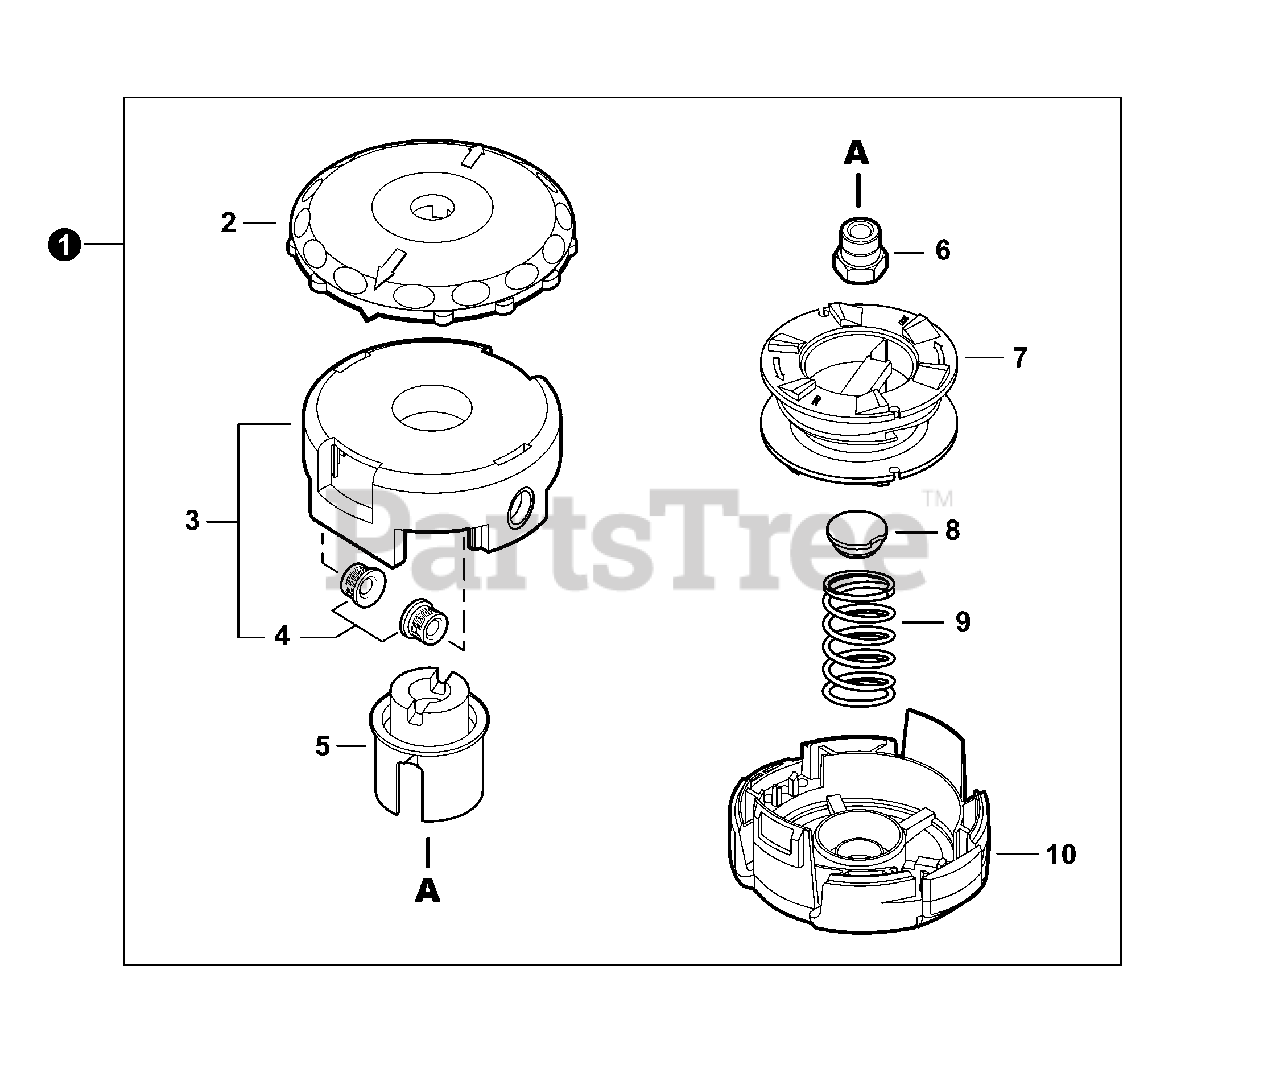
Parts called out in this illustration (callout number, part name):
1	TRIMMER HEAD, SPEED-FEED® 400
3	HOUSING ASSY, SPOOL
5	HUB (LH) BLACK
6	BUSHING M10×1.25 LH GOLD
8	CAP, SPRING
9	SPRING, GOLD
10	COVER, SPOOL
